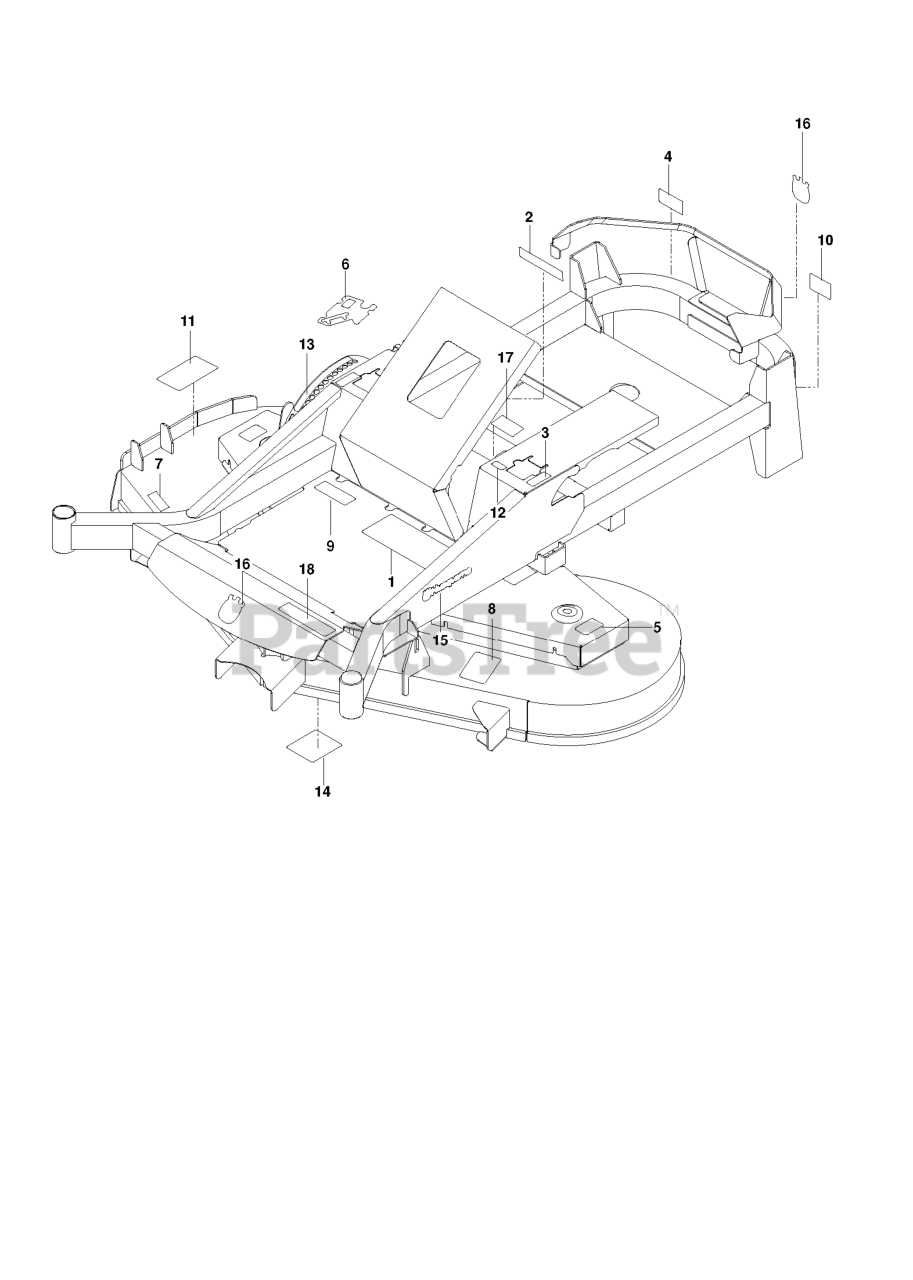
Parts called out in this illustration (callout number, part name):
1	DECAL, WARNING
2	EURO DECAL-BATTERY WARNIN6
3	DECAL, MOTION CONTROL
4	DECAL, BELT DRIVE
5	DECAL, NO STEP
6	DECAL, CONSOLE
7	DECAL, EURO SEVERING
8	DECAL, BELT ROUTING
10	DECAL
11	DECAL, CAUTION
12	DECAL, F.S.T.
13	DECAL, HEIGHT MZ, CE
14	DECAL, SERVICE
15	RP.DECAL.BADGE.170MM.TEXTLOGO
16	DECAL.AUGER.HUSQ.CROWN.SNOW
17	HG_DECAL, ZT-3400
18	DECAL, MZ 28T
